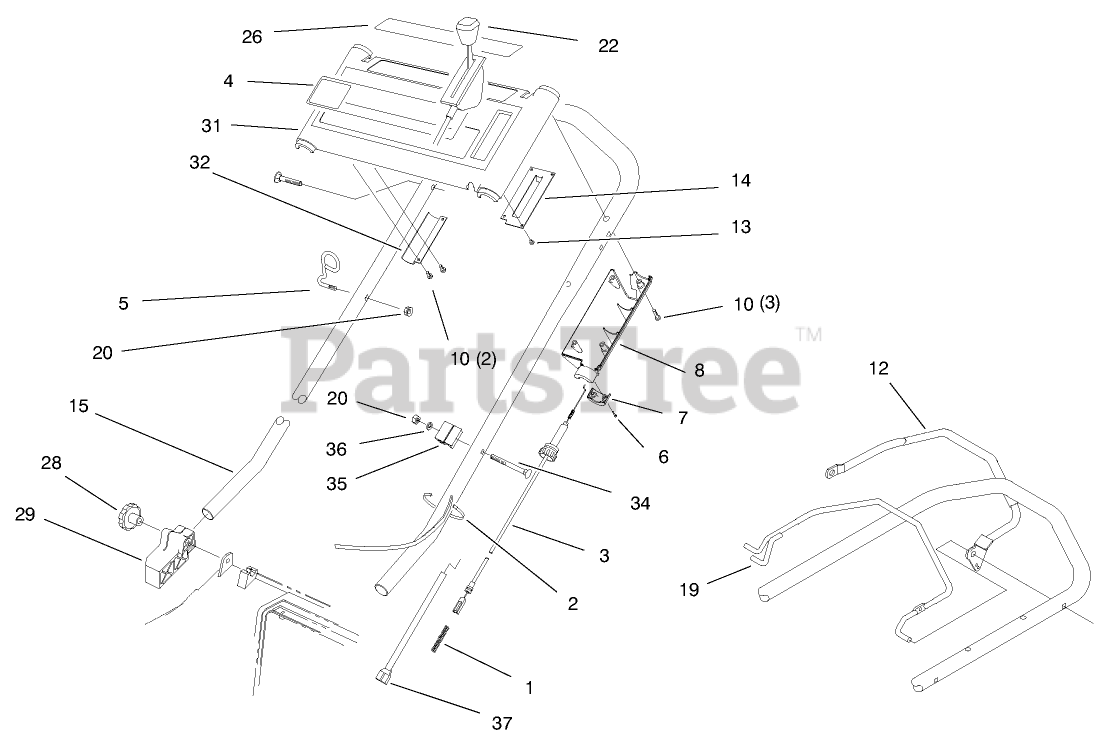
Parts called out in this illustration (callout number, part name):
1	SPRING-COMPRESSION
2	TIE-CABLE
3	CABLE - TRACTION
4	DECAL - PANEL
7	LOWER THROTTLE CAP
8	COVER-THROTTLE, LEVER
10	SCREW-PPH, PLASTITE
13	#6-19X.25 PLASK FORM SC
20	NUT-LOCK, NI
22	CONTROL - THROTTLE
26	DECAL - CONTROL PANEL
29	MOUNT-HANDLE, RH
34	SCREW
35	ANCHOR-CABLE, UPPER
36	WASHER-FLAT
37	CABLE - BRAKE
